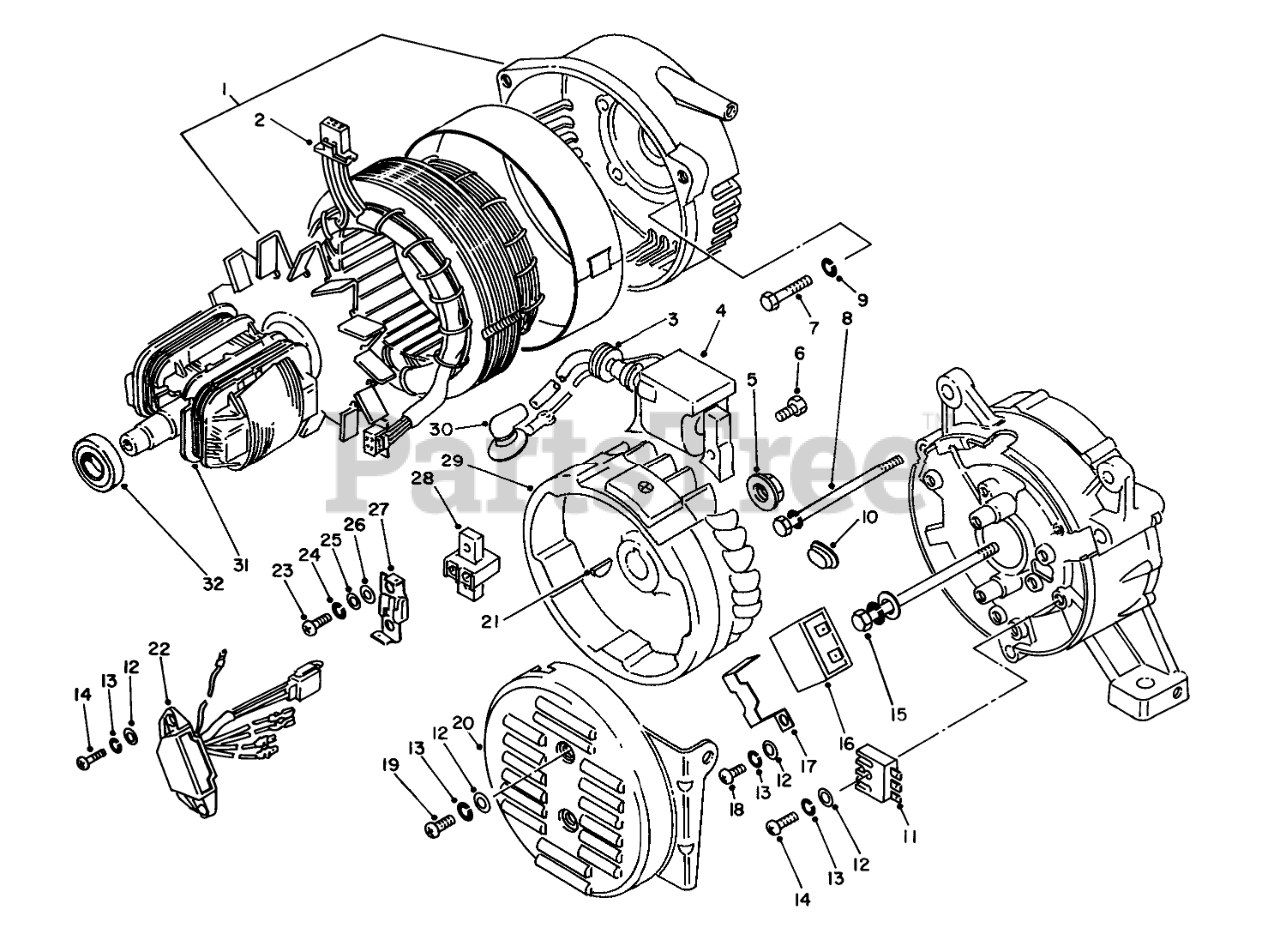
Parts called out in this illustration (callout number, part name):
1	Generator Assy (120V, 60Hz)
2	Stator-Generator (120V)
3	Grommet
4	Stator Assy (Incl. Ref. #3)
8	Bolt-Stator
9	Lockwasher
11	Diode
12	WASHER
13	Washer
14	Screw
15	Bolt-Rotor
16	CAPACITOR
17	Bracket
18	SCREW
19	Screw
20	Cover-Rear
22	REGULATOR
23	Screw
24	Lockwasher
25	Washer
26	Bushing
27	BRUSH
28	Holder-Brush
29	Rotor
30	Cap-Spark Plug
31	Rotor (Incl. Ref. #32)
32	Bearing
